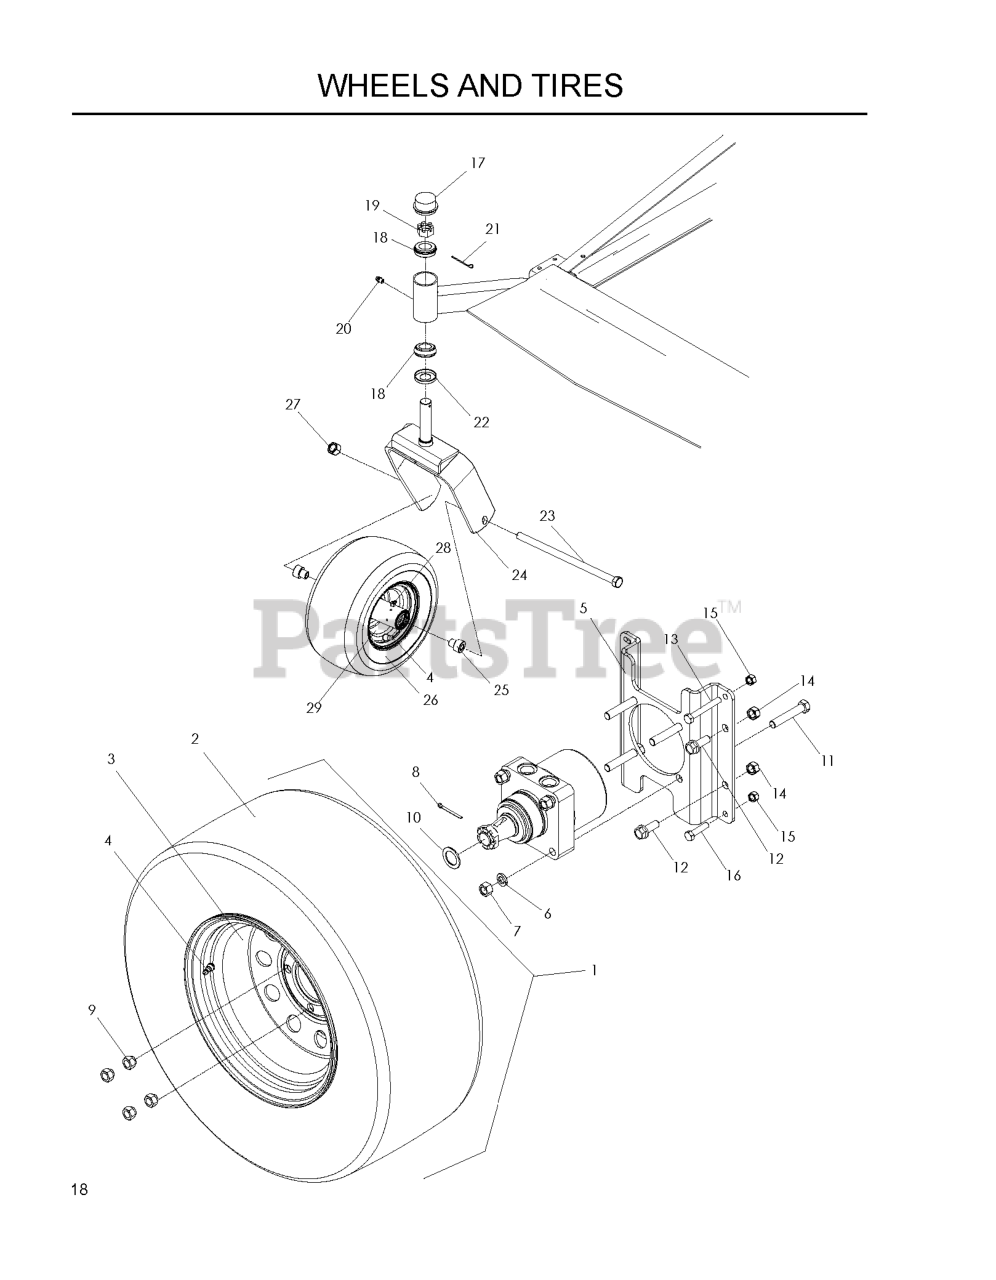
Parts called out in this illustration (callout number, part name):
1	WHEEL/TIRE.ASM.23X9.5-12.GREY
2	TIRE.TURF.MASTER.23X9.5-12
3	RIM, 12 X 7, 1" NEG OFFSET
4	VALVE STEM TR-412
5	MOUNT, MOTOR, WHEEL - BLK
6	WASHER 1/2" SPLIT LOCK
7	NUT HEX 1/2
8	PIN COTTER 4MM X 45MM
9	LUG NUT 1/2F
10	MACHINE BUSHING
11	HCS 1/2C X 2 3/4
12	HCS 1/2C X 1 1/4 SERRATED HEAD
13	HCS 3/8C X 2 1/4
14	NUT 1/2-13 HEX NYLOC ZD
15	NUT 3/8-16 NYLOC
16	HCS 3/8C X 1 1/4 GR5
17	GREASE CAP
18	TAPERED ROLLER BRG
19	NUT 1"C HEX SLOTTED
21	COTTER PIN 1/8 X 2
23	HEX SCREW 1/2-13 X 9.5 GR5
24	CASTOR YOKE ORANGE
25	AXLE SPACER
26	FRONT TIRE ASSY
27	NUT 1/2-13 HEX NYLOC ZD
28	ZERK
